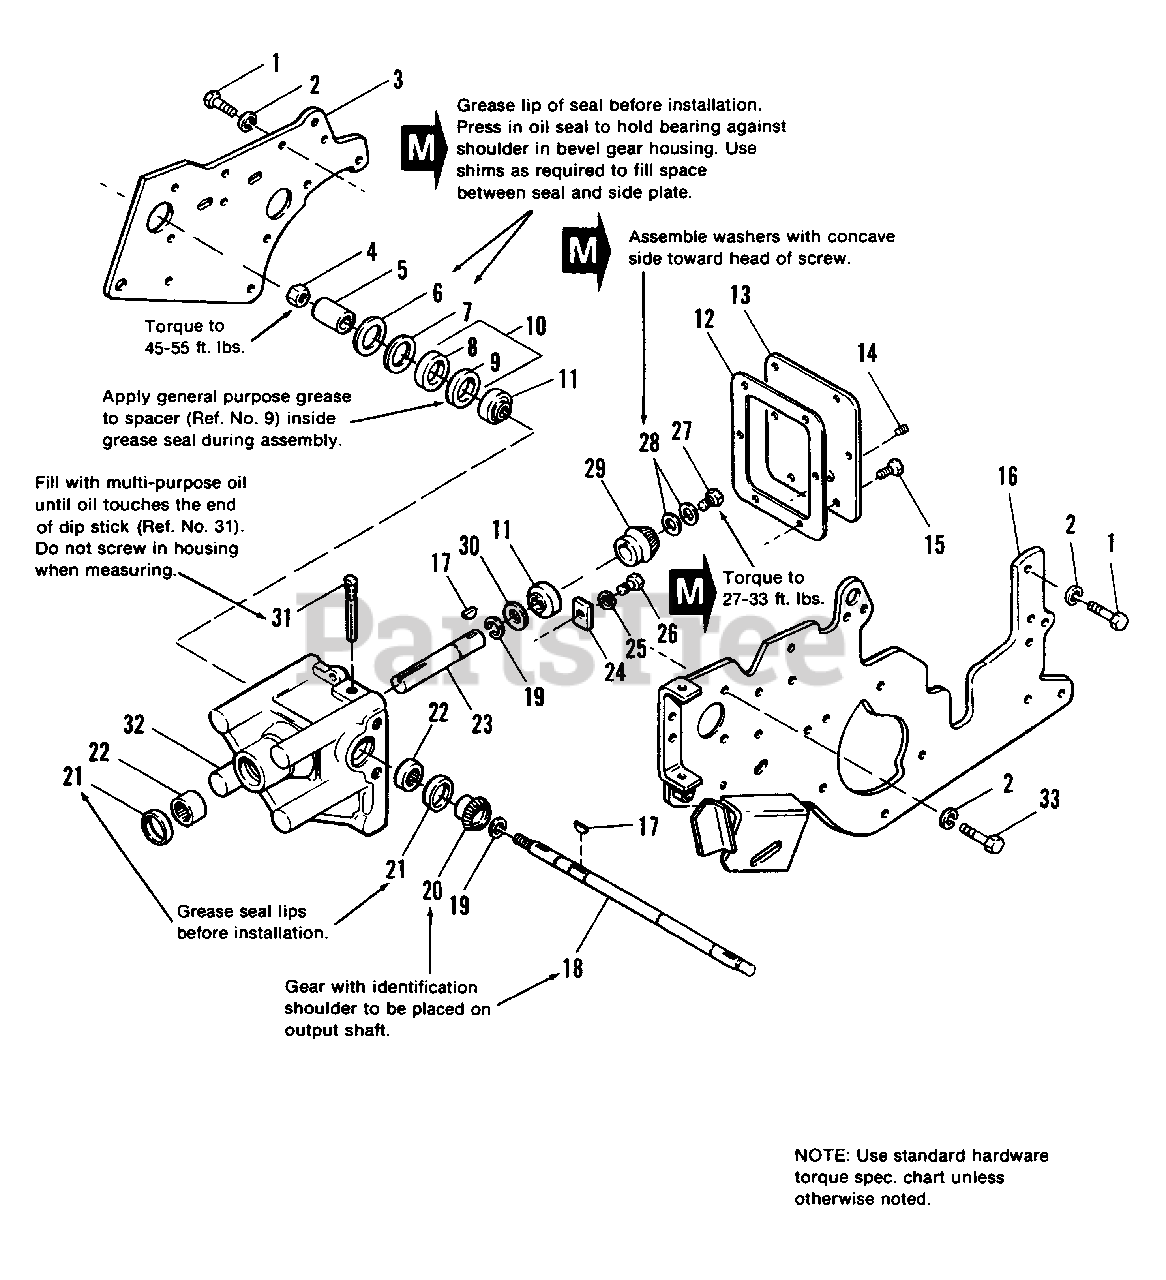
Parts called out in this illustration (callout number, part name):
1	CAPSCREW, Hex Hd., 7/16-14 x 1-1/4
2	LOCKWASHER, 7/16
3	PLATE, Side, RH
4	LOCKNUT, Hex, Jam, 3/4-16
9	SPACER, Seal, Oil
10	REPAIR KIT, Seal
11	BEARING, Ball
14	PLUG, Pipe (if equipped)
15	CAPSCREW, Hex hd., 1/4-20 x 5/8
16	PLATE ASSY., Side, LH
17	KEY, Woodruff, #9
18	SHAFT, Driven
19	RING, Retaining
20	GEAR, Bevel, Driven
22	BEARING, Needle
23	SHAFT, Driver
24	PLATE, Bearing, Clamp
25	LOCKWASHER, 5/16
26	CAPSCREW, Hex Hd., 5/16-18 x 5/8
27	CAPSCREW, Hex Hd., 5/16-18 x 3/4
29	GEAR, Bevel, Driver
32	HOUSING, Bevel Gear
33	CAPSCREW, Hex Hd., 7/16-14 x 1
